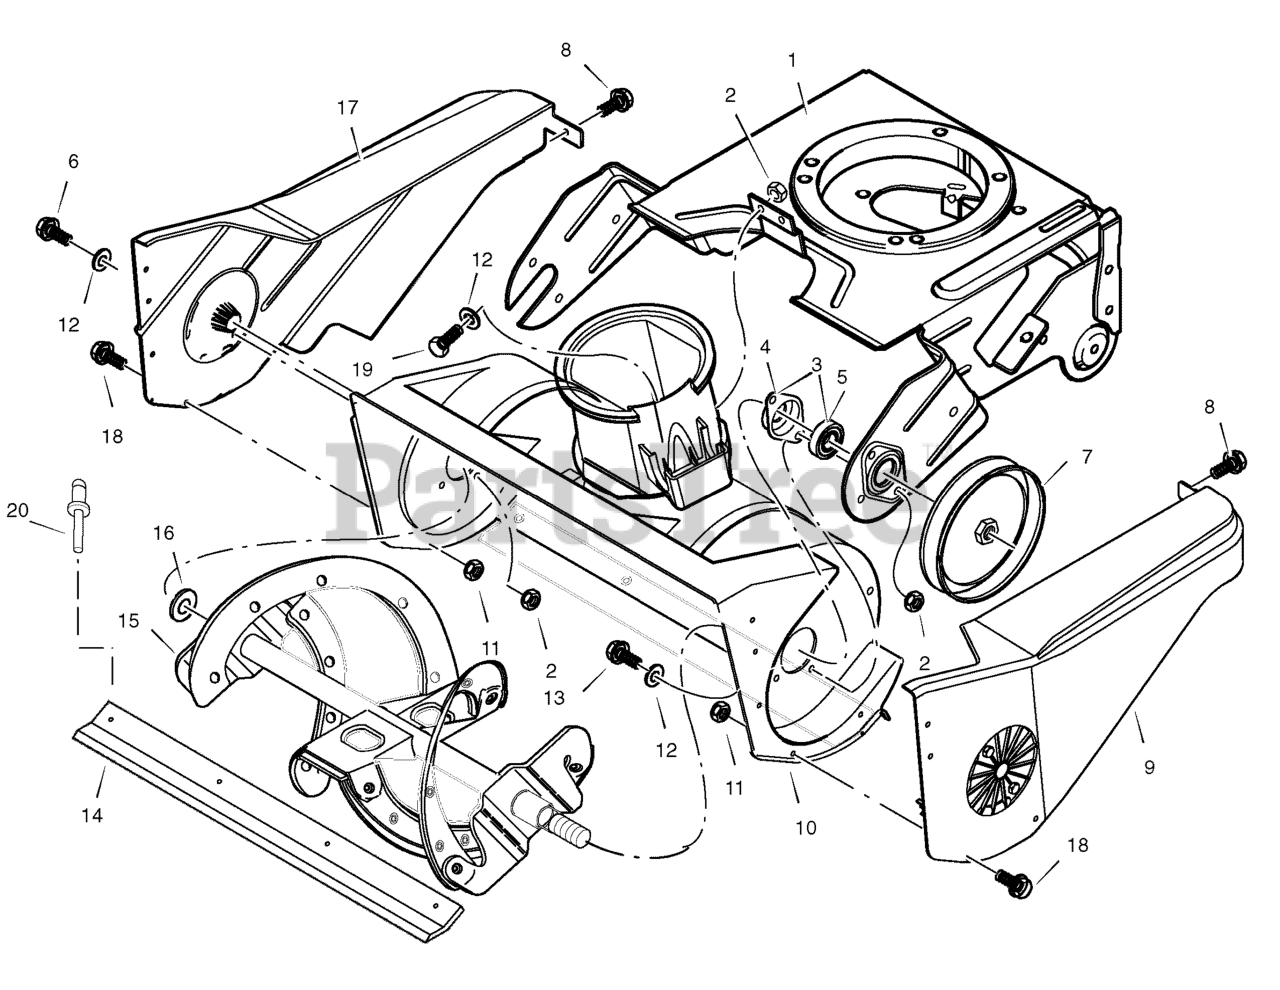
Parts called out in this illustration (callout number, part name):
1	FRAME, Motor Box
2	NUT, Hex Flange, Centerlock, 1/4-20
3	BEARING & RETAINER ASSEMBLY
4	RETAINER, Bearing
5	BEARING
6	CAPSCREW, Hex Head, 1/4-20 x 3/4
7	PULLEY, Auger
8	SCREW, Self Tap, 1/4-20
9	COVER, Belt, L.H.
10	AUGER HOUSING ASSEMBLY
11	NUT, Hex, Centerlock, 10-24
12	WASHER, Flat
13	CAPSCREW, Hex Head, 1/4-20 x 5/8
14	BLADE, Scraper
15	AUGER ASSEMBLY
17	COVER, Belt, R.H.
18	CAPSCREW, Hex Washer Head, 10-24 x 1/2
19	CAPSCREW, Hex Head, 1/4-20 x 3/4
